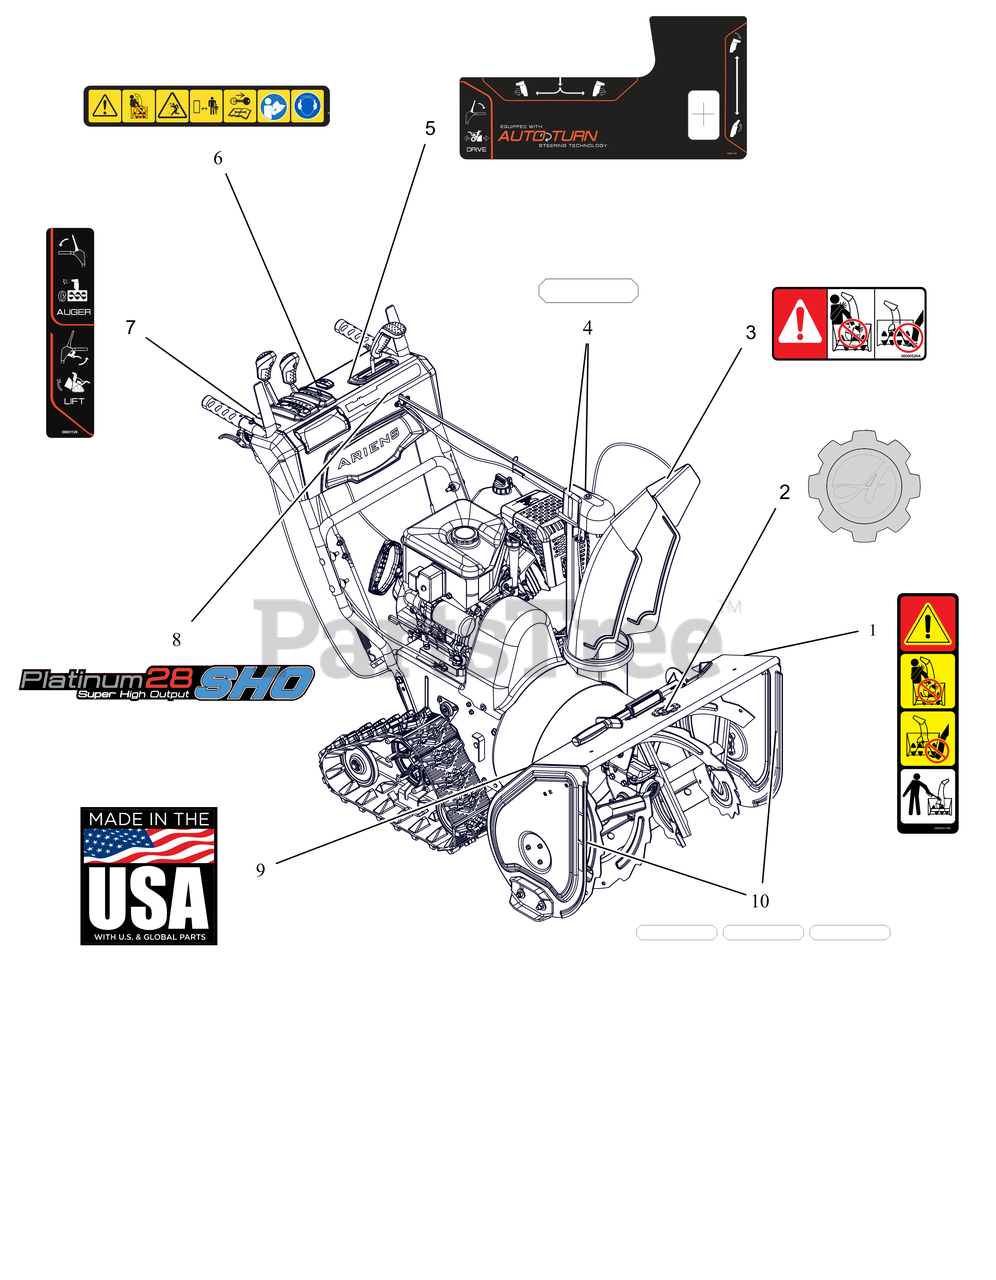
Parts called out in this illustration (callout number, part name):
1	DECAL, DANGER - ROTATING PARTS
2	DECAL, ARIENS-GEAR BADGE -THK
3	DECAL, DANGER
4	DECAL,REFLECTIVE,GEAR COVER
5	DECAL,CONTROL-LG QT2
6	DECAL,DASH - SAFETY
7	DECAL,CONTROL-RH TRACK
8	DECAL, DASH, PLATINUM 28 SHO
9	DECAL, MADE IN USA
10	DECAL,REFLECTIVE,HOUSING
